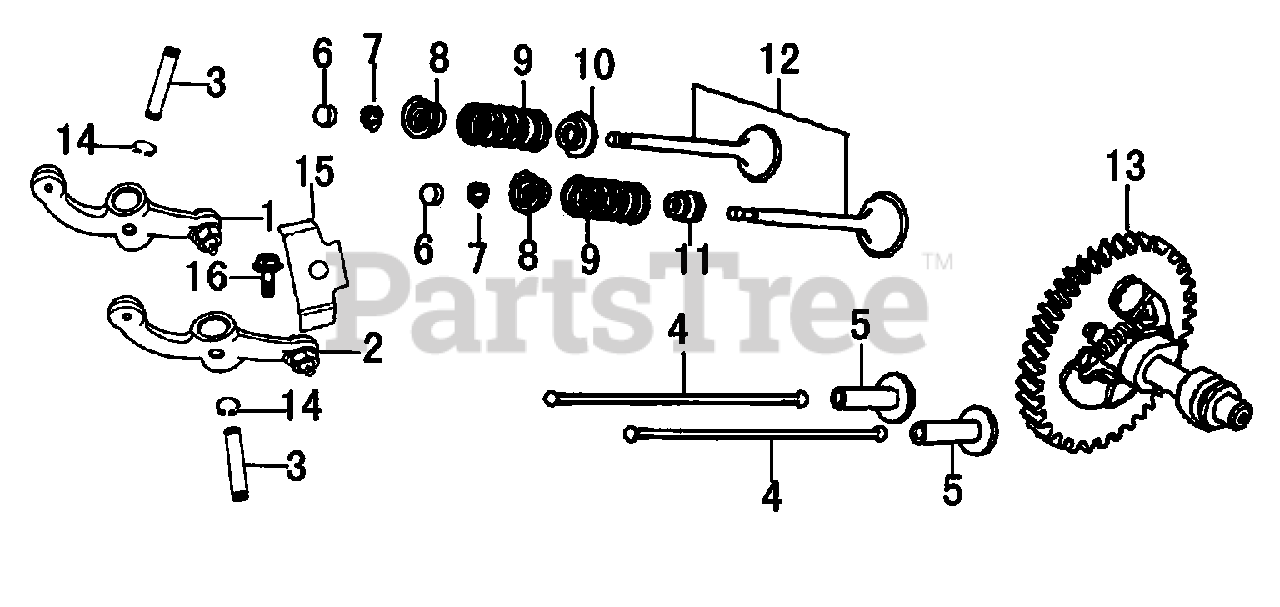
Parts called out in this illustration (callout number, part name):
1	ROCKER ARM ASSY.
2	ROCKER ARM ASSY.
3	SHAFT, VALVE ROCKER
5	LIFTER, VALVE
6	ROTATOR, VALVE
7	LOCKER, VALVE
8	RETAINER, VALVE SPRING
9	SPRING, VALVE
10	SEAT, VALVE SPRING
11	SEAL, VALVE STEM
12	VALVE ASSY.
13	CAMSHAFT ASSY
15	RETAINER, ROCKER ARM SHAFT
16	BOLT, FLANGE
